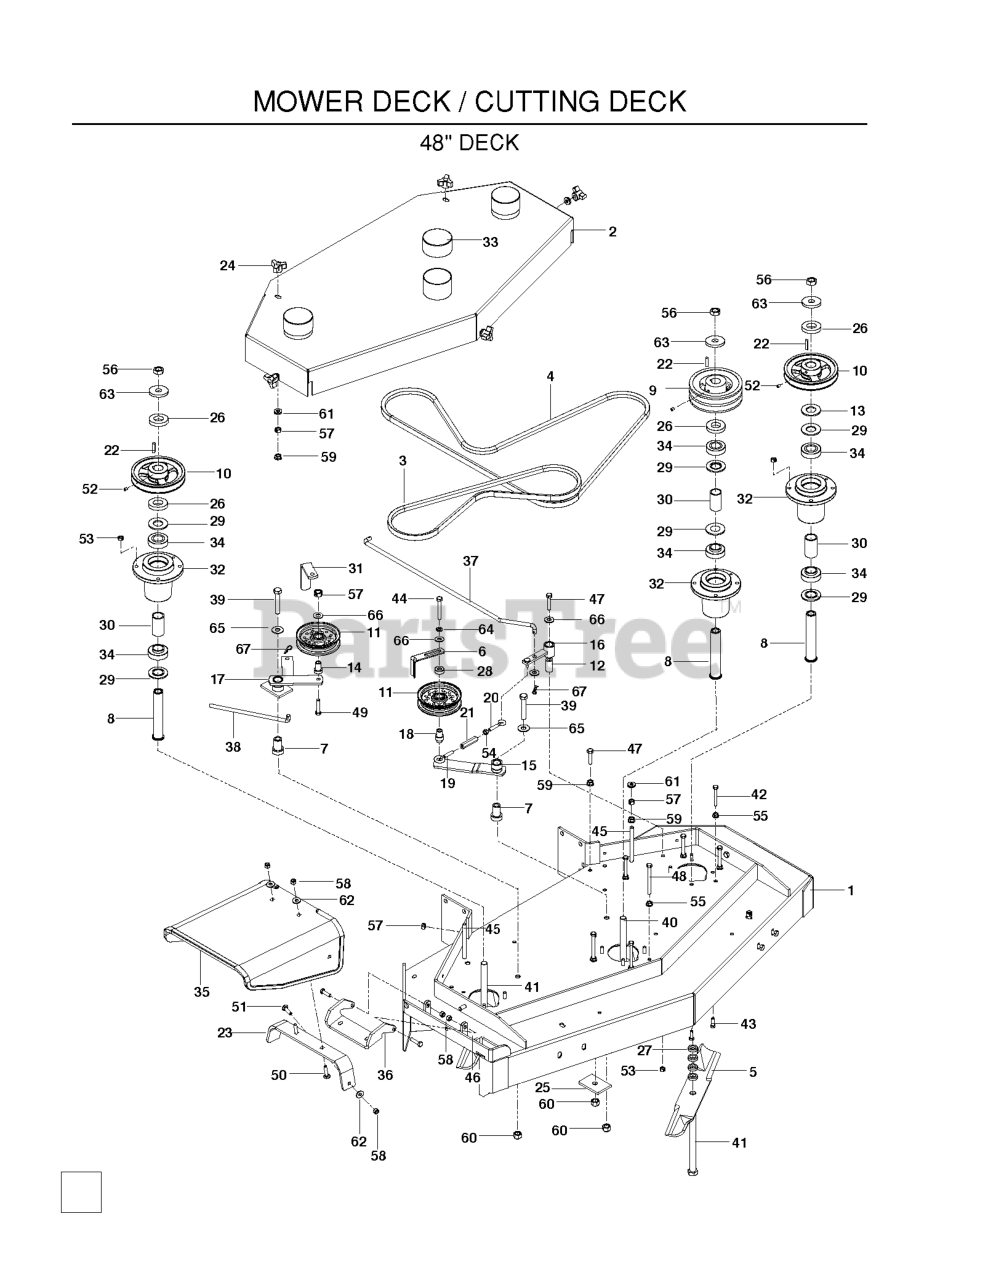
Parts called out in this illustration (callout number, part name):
1	DECK W/DECALS 48"
2	BELT SHIELD 48"
3	BELT, AUX BLADE
4	BELT - ENG/DECK 48
5	BLADE OEM 16 1/4"
7	IDLER SPINDLE
8	SPINDLE SHAFT
9	PULLEY, DOUBLE W/SETS
10	PULLEY W/SETSCREWS
11	IDLER PULLEY
12	BUSHING, SLEEVE
13	MACHINERY BUSHING 10 GA.
14	BUSHING, IDLER FLANGE
15	ARM WELDMENT
16	ENGAGEMENT ARM
17	IDLER ARM, AUX.
18	EYEBOLT PIVOT
19	EYEBOLT, LH
20	EYEBOLT, RH
21	TURNBUCKLE
22	KEY 1/4 SQ X 1 1/8
23	BRKT, REINF-CHUTE WB
24	KNOB, THREE PRONG
27	BLADE SPACERS
29	COMBO SPACER
31	BELT GUIDE, SHORT
32	HOUSING, DIE CAST
34	BEARING-ECC LOCK W/COLLAR
35	CHUTE, RUBBER DISCHARGE WB
36	PIVOT BRACKET - CHUTE
37	BLADE ROD 48"
38	TENSION ROD
39	HCS 1/2C X 2 3/4
40	HCS 5/8-18 X 9 GR5 ZD
41	HCS 5/8F X 8 1/2
42	HCS 5/16 X 3
43	HCS 5/16C X 1
44	HCS 3/8C X 2 1/2
45	TAPBOLT 3/8C X 4 1/2
46	HCS 5/16C X 1 1/4
47	HCS 3/8C X 2 1/4
48	HCS 5/16C X 4
49	HCS 3/8-16 X 1 3/4 GR5
50	RHSNB 5/16-18 X 1-1/2 GR 5 ZD
51	BOLT, CARRIAGE 5/16X1-1/4
52	SET SCREW 5/16 NYLOC
53	NUT 5/16C CENTERLOCK
54	NUT 5/16C HEX
55	NUT 5/16C WHIZ
56	NUT 5/8F HEX
57	NUT 3/8C CENTERBLOCK
58	NUT 5/16 NYLOC
59	NUT 3/8C WHIZ
60	NUT 1/2-13 HEX NYLOC ZD
61	WASHER, 3/8 SEALING
62	WASHER 5/16 FLAT
63	WASHER, SUPPORT
64	SLW 3/8 STD
65	WASHER 1/2 FLAT
66	WASHER 3/8 FLAT
67	HAIRPIN #2
